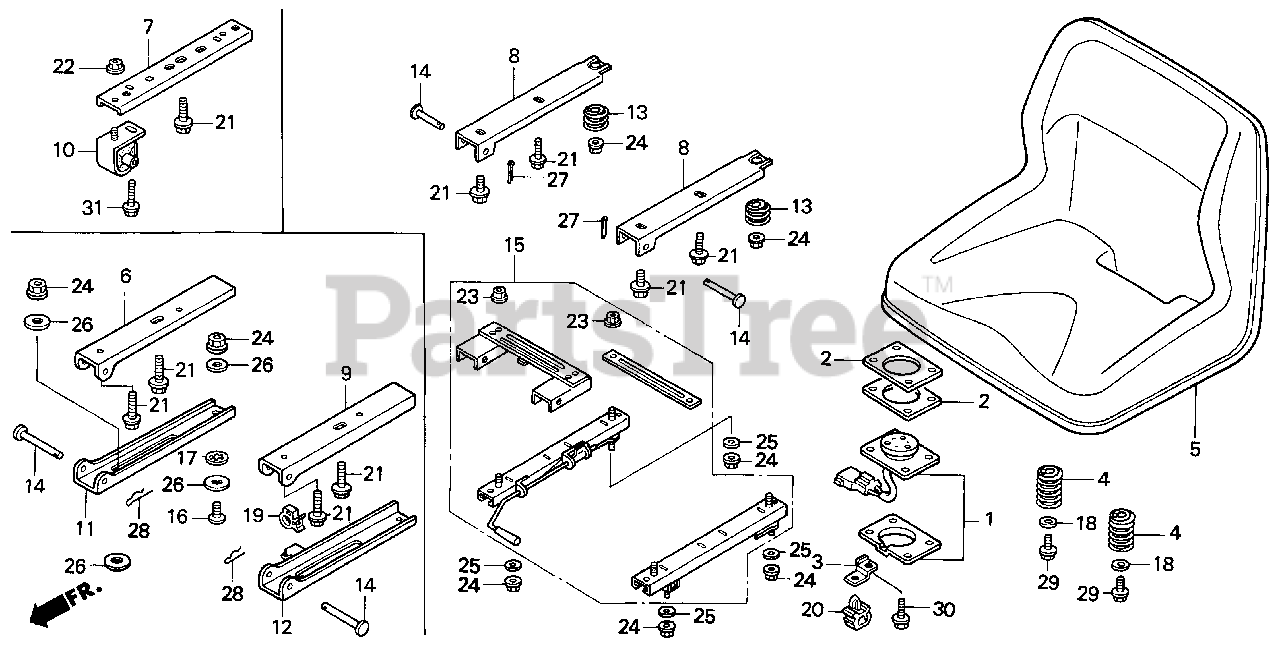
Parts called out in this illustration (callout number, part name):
1	SWITCH ASSY., SEAT
2	SPACER, SEAT SWITCH
3	BASE, CLIP
4	SPRING, SEAT
5	SEAT ASSY.
6	HINGE, R. SEAT (UPPER)
7	HINGE, SEAT (UPPER)
9	HINGE, L. SEAT (UPPER)
10	MOUNT, SEAT
11	HINGE, R. SEAT (LOWER)
12	HINGE, L. SEAT (LOWER)
14	PIN, SEAT HINGE (8X57)
16	BOLT, SPECIAL (8X20)
17	WASHER, THRUST
18	WASHER (6X20)
19	CLIP, CABLE (10MM)
20	CLIP, HARNESS (7MM)
21	BOLT-WASHER (8X16)
22	NUT, FLANGE (6MM)
24	NUT, FLANGE (8MM)
26	WASHER, PLAIN (8MM)
28	PIN, LOCK (8MM)
29	BOLT, FLANGE (6X18)
30	BOLT, FLANGE (6X22)
31	BOLT, FLANGE (8X16)
